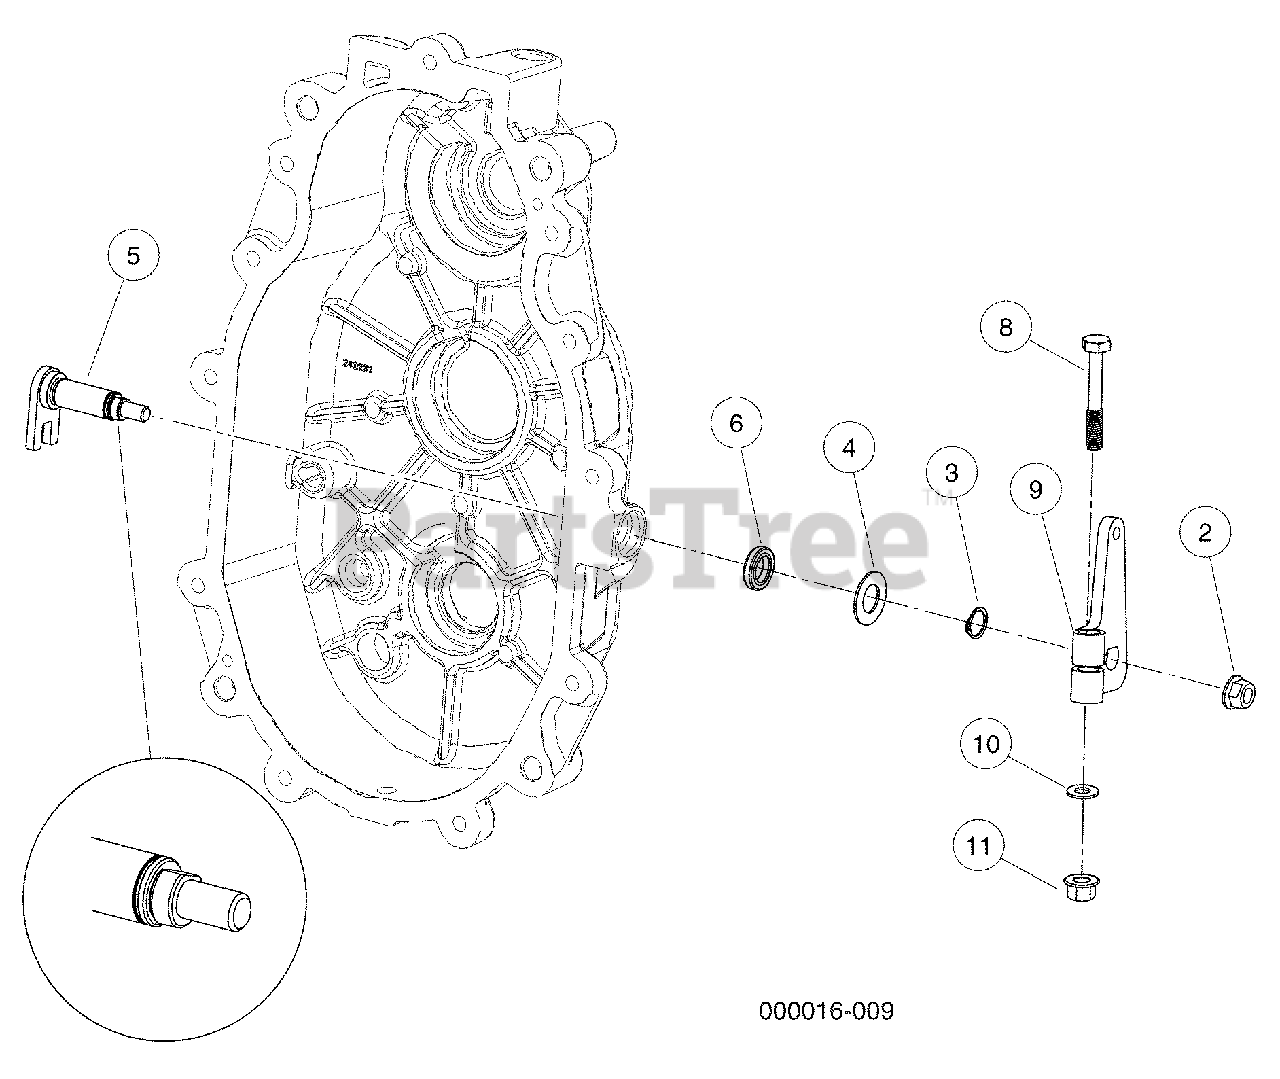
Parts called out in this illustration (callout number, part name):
1	Kit, Trans Shift Shaft Repair
2	Nut, Lock Hex, Nylon, 5/16-24
3	Ring, Retaining, External 9/16
4	Washer, Flat, .58 X 1.08 X .05
5	Weldment, Shift, Shaft
6	Seal, Dul Lip, .88 X .56 X .19
7	Kit, Bellcrank, D Shape, Clamp
8	Bolt, 3/8-16 X 2.00 Hex Head
9	Asm, Bellcrank, D Shape, Clamp
10	Washer, 3/8 Type A Flat
11	Locknut, 3/8-16 Hex
